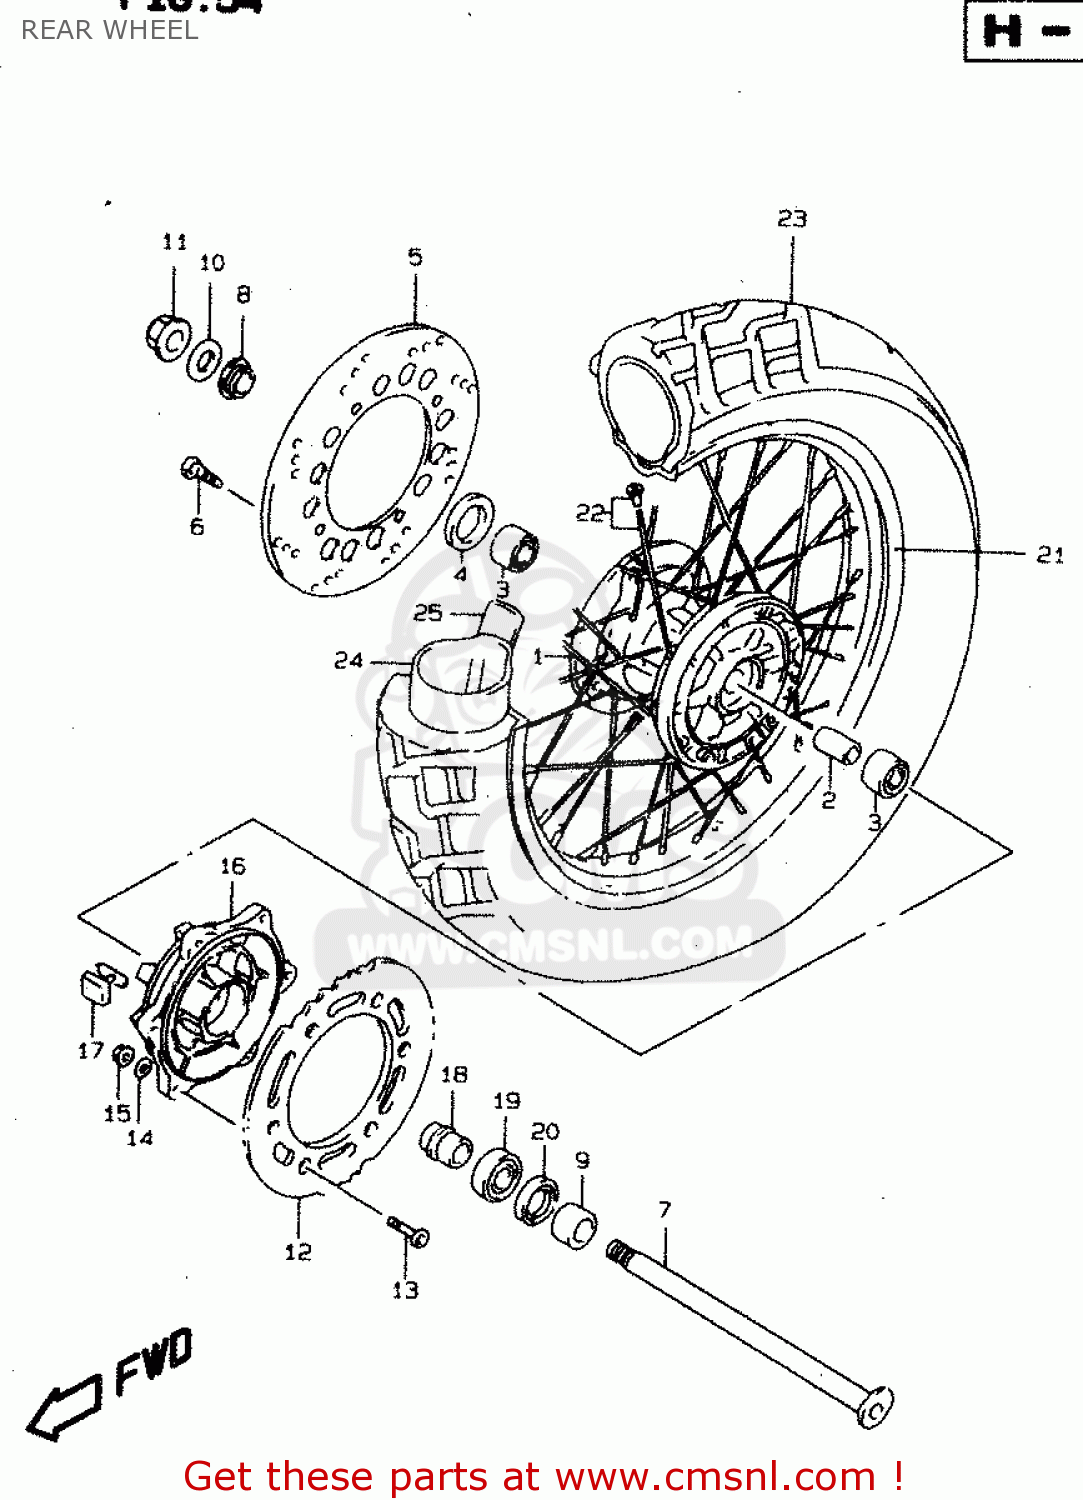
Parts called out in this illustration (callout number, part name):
1	HUB,RR WHEEL
2	SPACER,RR HUB BEARING
3	BEARING
4	SEAL,OIL(26X47X5)
5	DISC,RR BRAKE
6	BOLT,BRAKE DISC
7	AXLE,RR
8	SPACER,RR AXLE,R
9	SPACER,RR AXLE,L
10	WASHER(19X32X3.2)
11	NUT 18MM
12	SPROCKET,RR(NT43-525)
13	BOLT(8X30.5)
14	WASHER
15	NUT
16	DRUM,RR SPROCKET MOUNTING
17	ABSORBER,RR HUB SHOCK
18	RETAINER,RR SPROCKET DRUM
19	BEARING(25X52X15)
20	SEAL,OIL(34X52X6)
21	RIM, REAR WHEEL (MT3.00X17) (BLACK)
22	SPOKE SET,RR WHEEL
23	TIRE, REAR (PIRELLI) (130/80 R17 65H MT8
24	TUBE ASSY, WHEEL INNER (PIRELLI)
25	PROTECTOR, INNER TUBE (PIRELLI)
